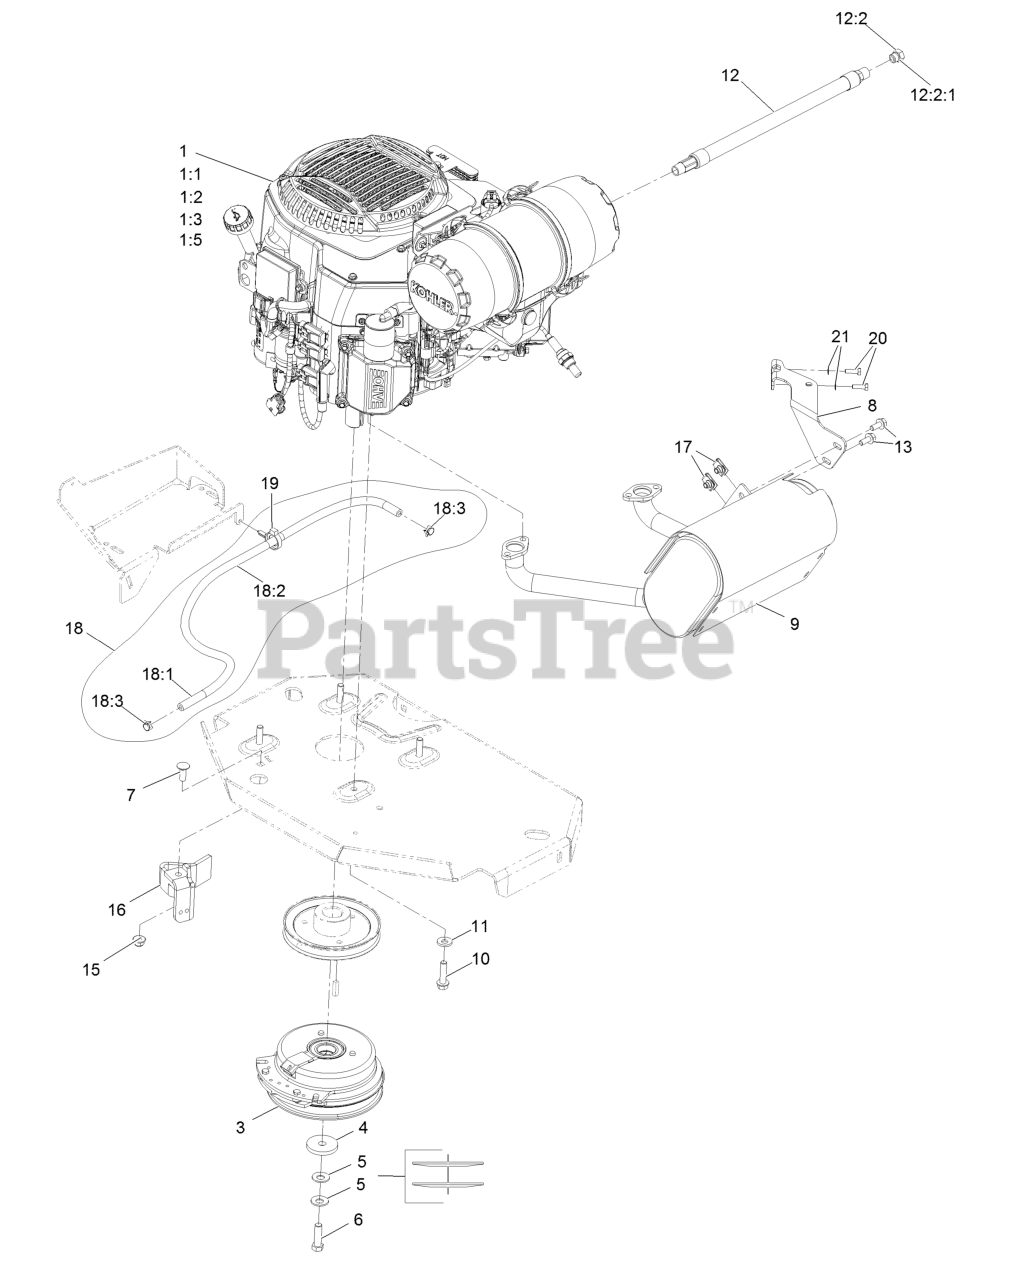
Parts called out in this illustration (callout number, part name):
1:1	Kohler 52 050 02-S Engine Oil Filter
1:2	Kohler 25 083 01-S Engine Air Filter
1:3	Kohler 25 083 04-S Safety Filter
1:5	Kohler 25 050 42-S Fuel Filter
3	Clutch Kit
4	Washer-Clutch
5	Washer-Spring Disc 7/16
6	Screw-HH 7/16-20 X 1 1/2 W/Loctite
7	Bolt-Carriage 3/8-16 X 1
8	Muffler Bracket Kit
9	Muffler Kit
10	Screw-HWH 3/8-16 X 1 1/2 Taptite
11	Washer-Spring Disc 3/8
12	Oil Drain Hose ASM
12:2	Plug-W/O-Ring
12:2:1	O-Ring
13	Screw-HH Flg 5/16-18 X 3/4
15	Nut-Nyloc 3/8-16 Flg
16	Clutch-Anchor
18	Fuel Line ASM
18:1	Hose-Fuel Line 38 1/4"
18:2	Sleeve-Thermal
18:3	Clamp-Hose
19	Clamp-Hose
20	Screw-HH M6-1 X 20Mm W/Patch
21	Washer-Spring Disc 1/4
